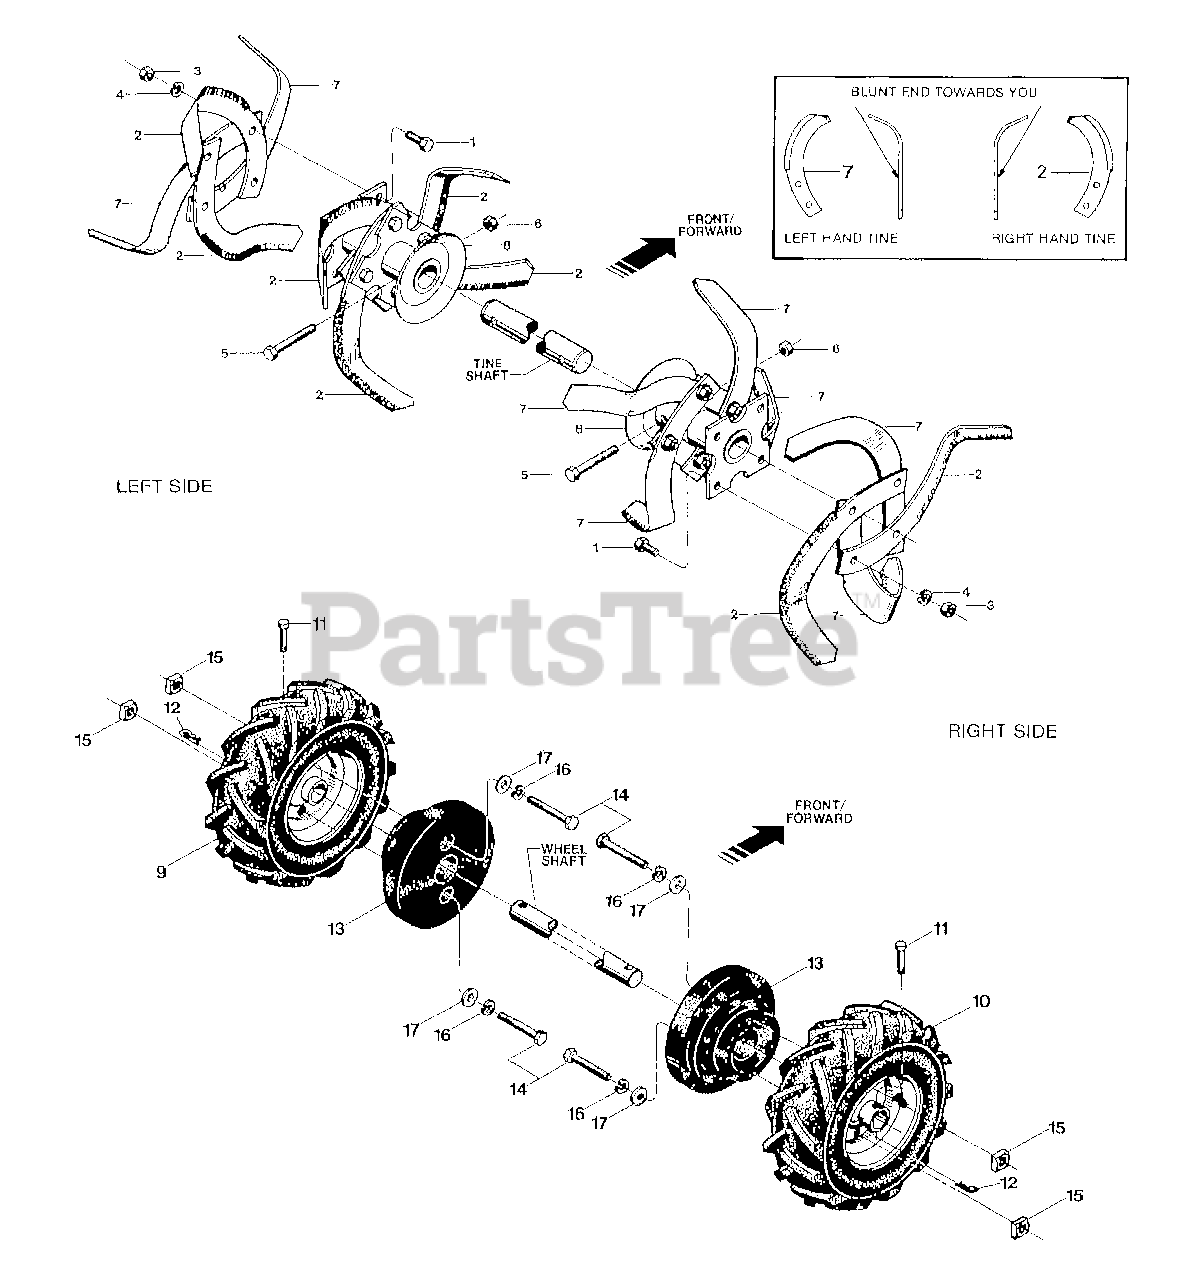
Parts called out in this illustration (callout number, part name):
1	SCR-HH 3/8-16X1.0 G5 ZP
1	SCR-HH 3/8-16X1-1/4" G5 ZP (1501004 & UP)
2	TINE-BOLO RT W/HDW
3	NUT-LOCK 3/8-16
4	WASHER-LK .375 @ DEPL
5	SCR-HH 3/8-16X2.00 G8
6	NUT-H/LK 3/8-16
7	TINE-BOLO LT W/HDW
8	WELD-TINE HOLDER ECONO (USE W/1.00" O.D. TINESHAFTS)
8	HOLDER-TINE ECONO RED (USE W/15/16" O.D. TINESHAFT)
9	ASSM-TIRE&WHEEL LH GRAY (15-20 LBS AIR REQ'D)
10	ASSM-TIRE&WHEEL RH GRAY (15-20 LBS AIR REQ'D)
11	PIN-CLEVIS
12	PIN-CLIP .08
13	WEIGHT-WHEEL
14	SCR-HH 3/8-16X3.0 G5 ZP
15	NUT-SQ 3/8-16
16	WASHER-LK .375 @ DEPL
17	WASHER-FLAT 3/8 SAE
